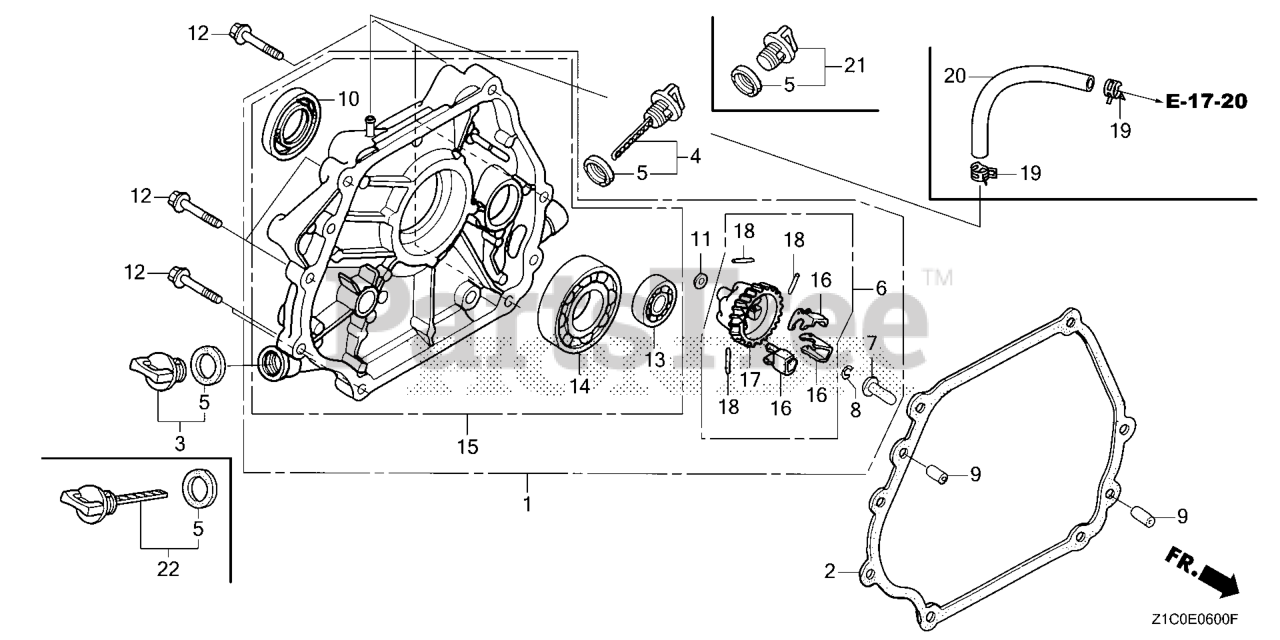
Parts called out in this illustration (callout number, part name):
1	COVER ASSY., CRANKCASE (S-TYPE)
2	GASKET, CRANKCASE COVER
3	CAP ASSY., OIL FILLER
4	CAP ASSY., OIL FILLER
5	GASKET, OIL FILLER CAP
6	GOVERNOR ASSY.
7	SLIDER, GOVERNOR
8	CLIP, GOVERNOR HOLDER
9	PIN, DOWEL (8X12)
10	OIL SEAL (35X52X8) (NOK)
11	WASHER, PLAIN (6MM)
12	BOLT, FLANGE (8X40) Use up to Engine SN 1003236.
13	BEARING, RADIAL BALL (6202)
13	BEARING, RADIAL BALL (6202) (FUJIKOSHI)
14	BEARING, RADIAL BALL (6207)
16	WEIGHT, GOVERNOR
17	HOLDER, GOVERNOR WEIGHT
18	PIN, GOVERNOR WEIGHT
